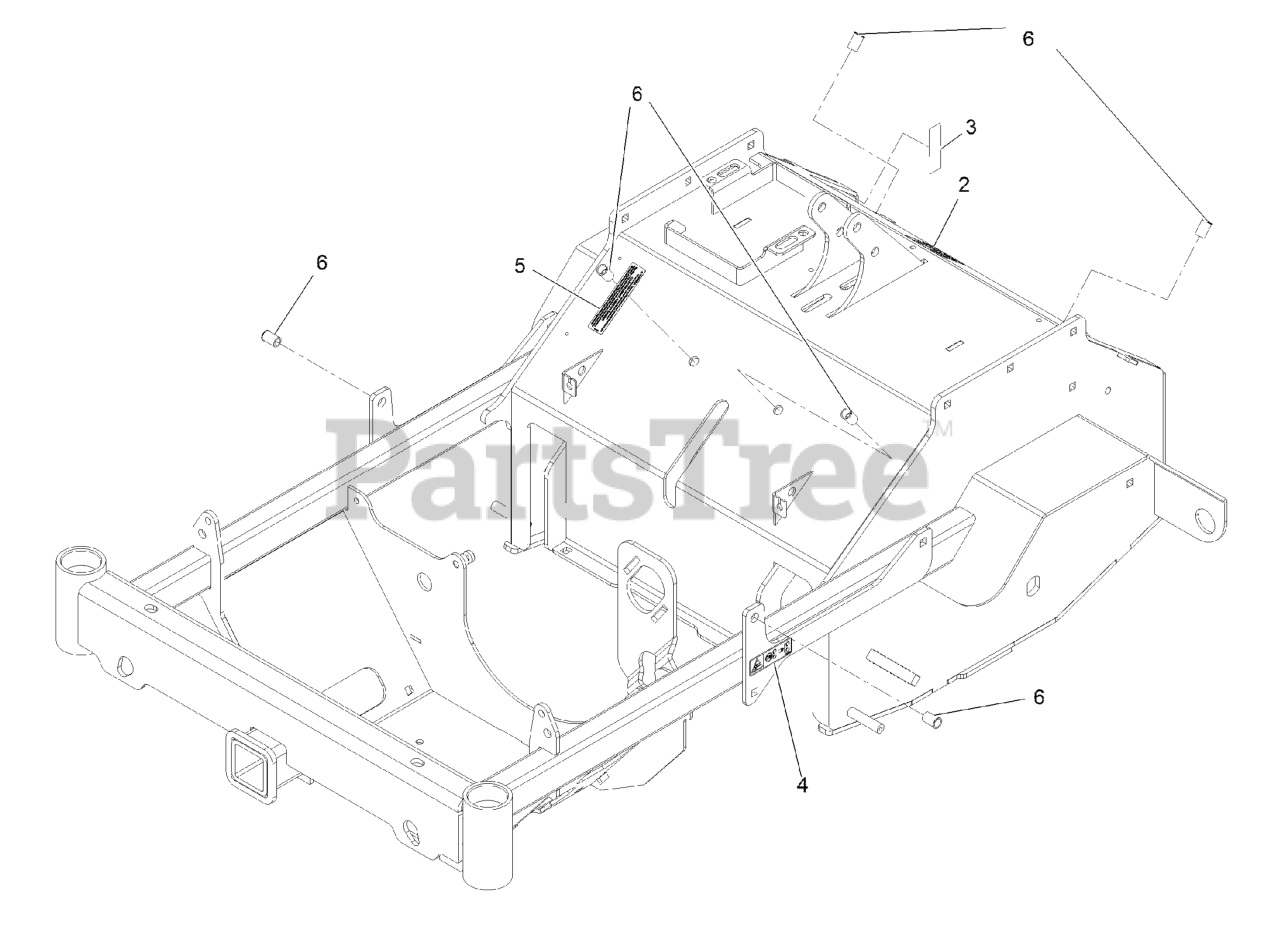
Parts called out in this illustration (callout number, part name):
2	DECAL-WARNING
3	DECAL-WARNING
4	DECAL-DANGER
5	DECAL-ARRESTOR, SPARK
6	NUT-CLINCH
